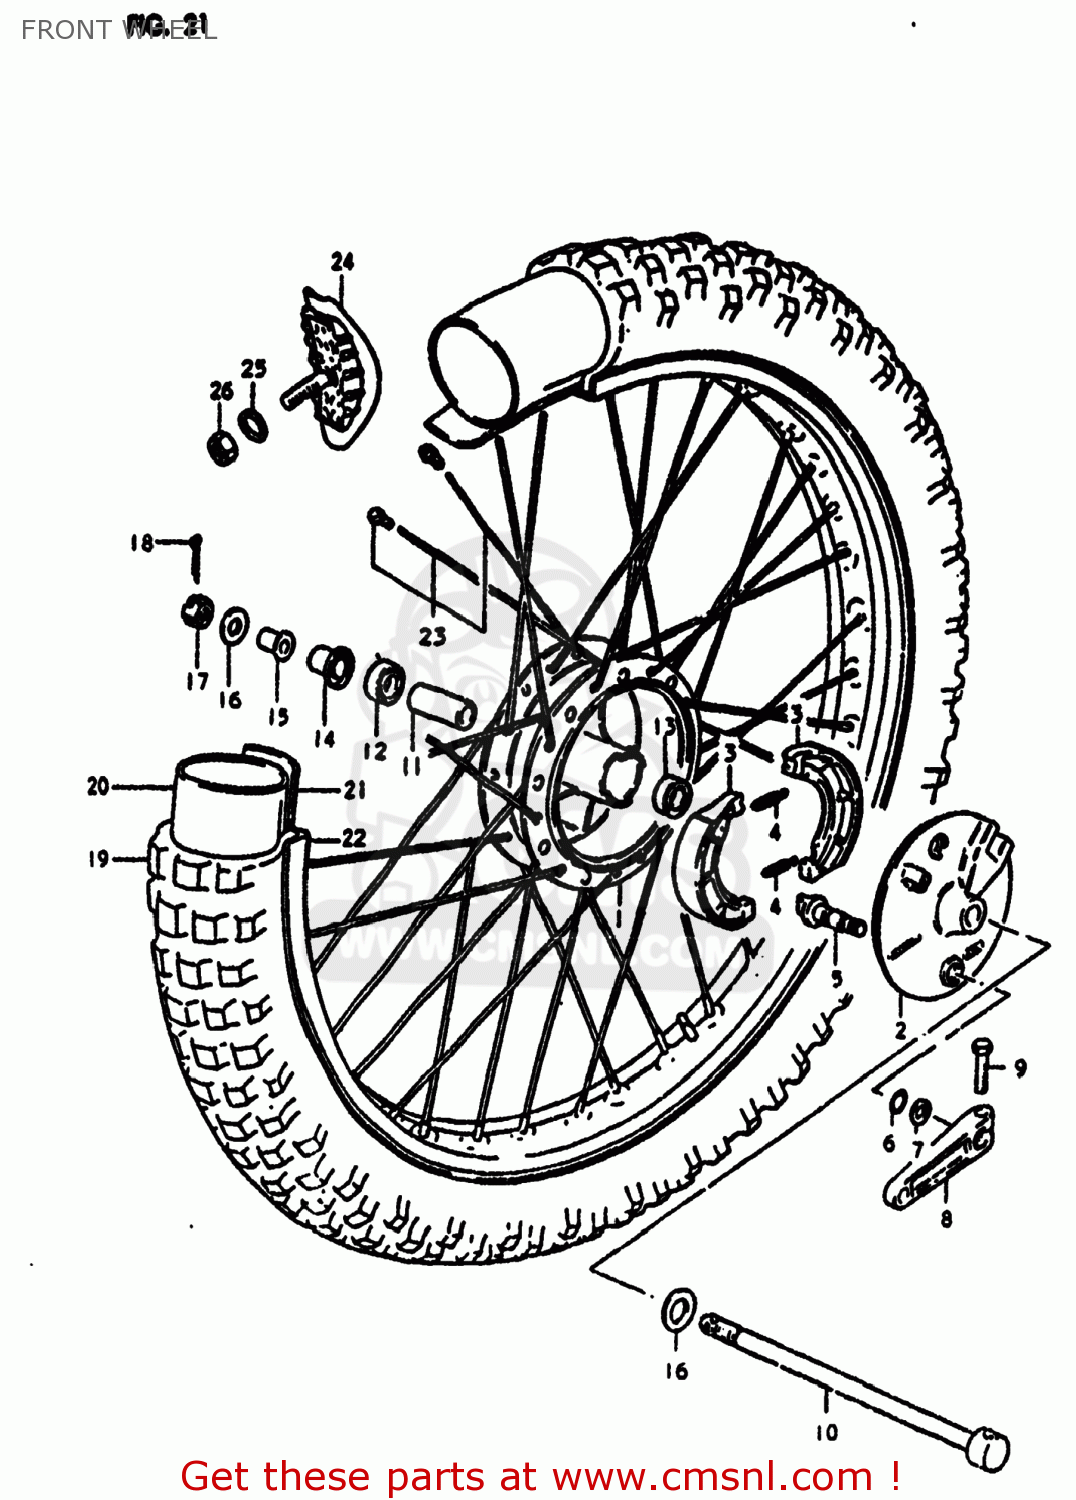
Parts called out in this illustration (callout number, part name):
1	DRUM,FRONT HUB
2	PANEL,FRONT HUB
3	SHOE,BRAKE
4	SPRING
5	CAM,FRONT BRAKE
6	O-RING,BOSS
7	WASHER (15X24X1.6)
8	LEVER,FRONT BRAKE CAM
9	BOLT
10	AXLE,FRONT
11	SPACER (12.6X19X52)
12	BEARING, RH
13	BEARING
14	SPACER,FRONT AXLE,RIGHT
15	SPACER,FRONT AXLE,LEFT
16	WASHER
17	NUT, REAR AXLE
18	COTTER PIN
19	TIRE,FRONT
20	TUBE,INNER
21	PROTECTOR,WHEEL,INNER
22	RIM,FRONT WHEEL
23	SPOKE SET,FRONT
24	STOPPER,BEAD
25	WASHER
26	NUT
